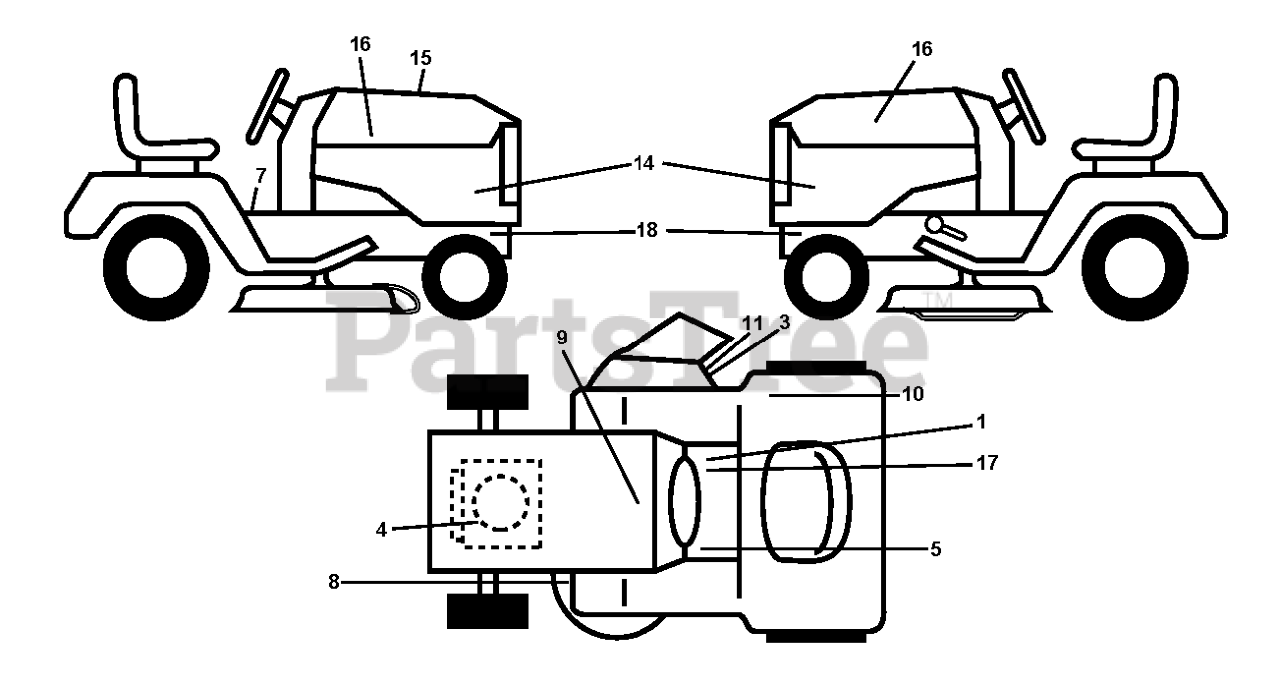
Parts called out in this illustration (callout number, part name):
1	DECAL
3	DECAL, DEFLECT WARNING
4	DECAL
5	DECAL
7	LABEL
8	DECAL.MOWER.SCH.48/54
9	DECAL BTRY SYMBOLS
10	DECAL.FENDER
11	DECAL.INTERNATIONL.CUTFINGER
16	RP.DECAL.BADGE.170MM.TEXTLOGO
17	DECAL PARK BRAKE
